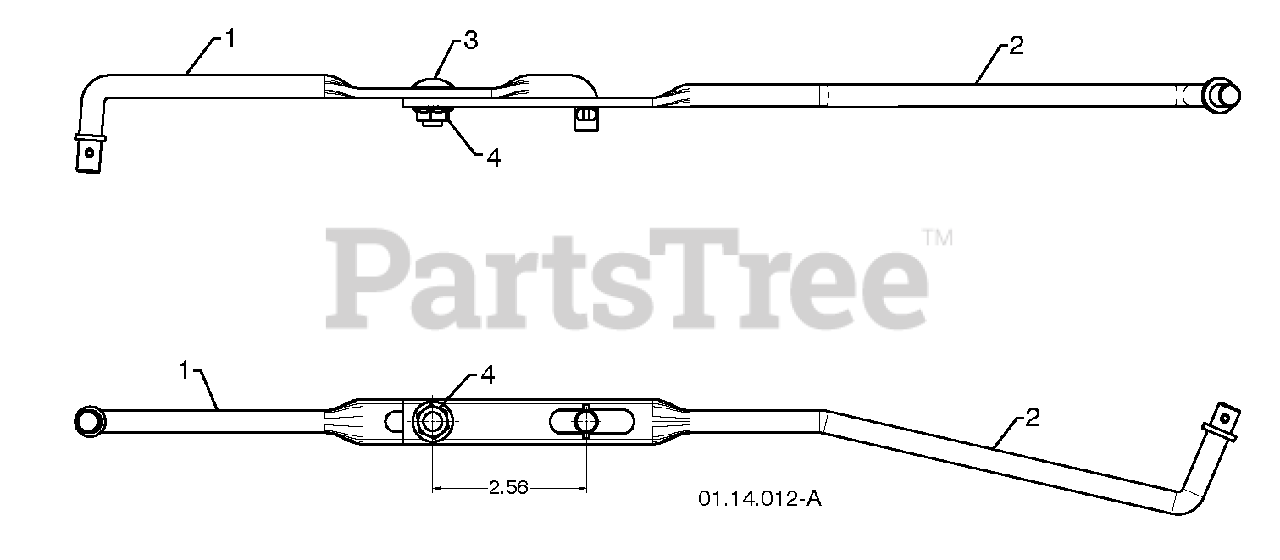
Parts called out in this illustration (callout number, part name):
1	SHIFTER ROD TOP
2	SHIFTER ROD BOTTOM
3	CARRIAGE BOLT 5/16-18 X .75
4	NUT 5/16-18
